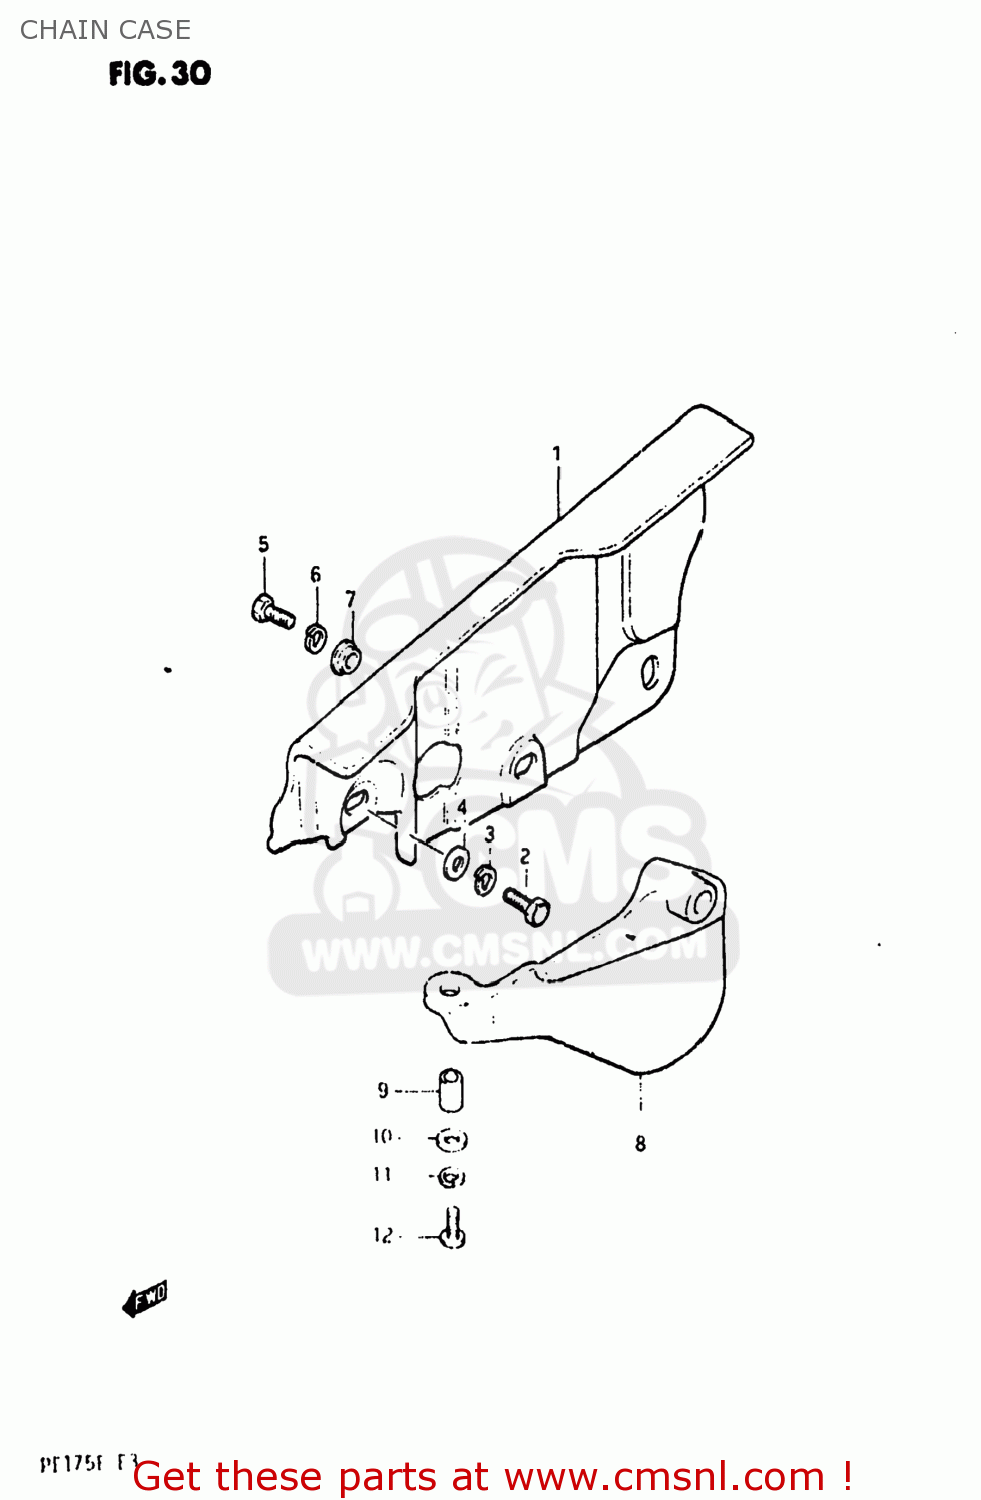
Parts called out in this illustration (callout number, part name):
1	CASE,CHAIN
2	BOLT, UPPER
3	LOCK WASHER
4	WASHER(6.5X18X1)
5	BOLT
6	LOCK WASHER
7	WASHER
8	RUBBER,CHAIN CASE,LOWER
9	SPACER (6.1X8X5.2)
10	WASHER(6.5X18X1)
11	LOCK WASHER
12	SCREW 6X12
